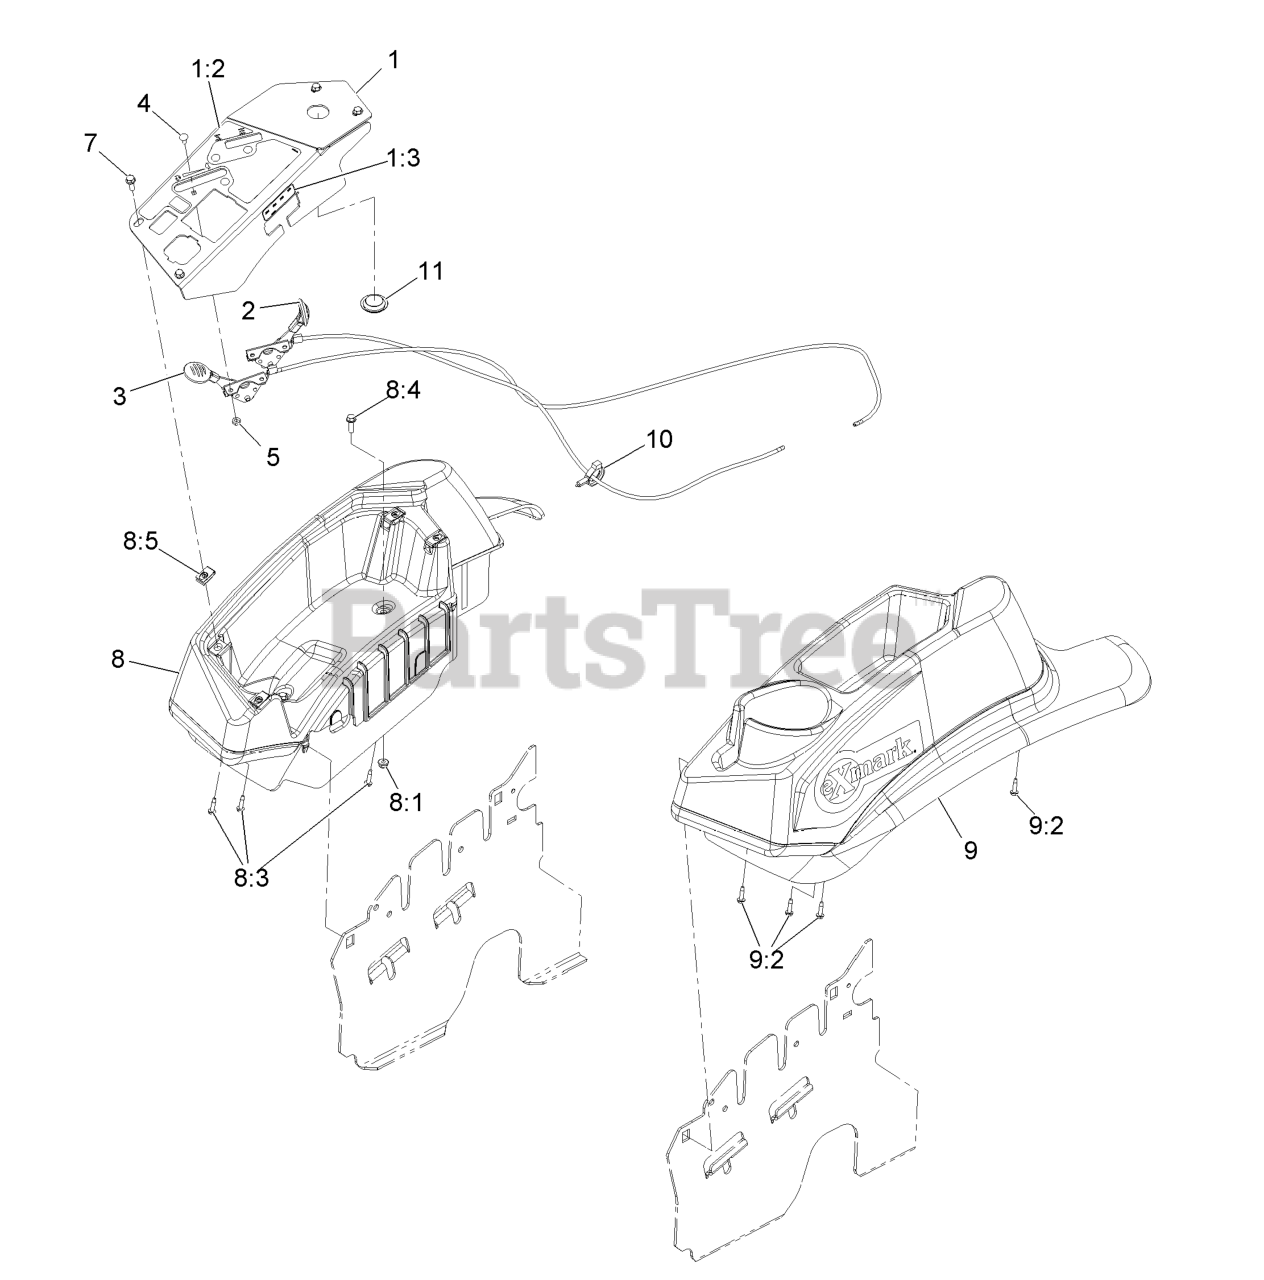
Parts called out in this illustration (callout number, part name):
1	CONSOLE,PANEL W/DECAL
1:2	DECAL-CONTROL PANEL
1:3	DECAL-FUSE
2	ASM, CHOKE CABLE
3	ASM,THROTTLE CABLE
4	BOLT-CARR
5	NUT-LOCK, NI
7	SCREW-HWH
8	CONSOLE,RH NARROW ASM
8:3	SCREW,THD FORM,HWH
8:4	SCREW-HWH
8:5	Nut-Retainer-Panel 1/4-20
9	CONSOLE.LH NARROW ASM
9:2	SCREW,THD FORM,HWH
10	CLAMP-HOSE
11	PLUG-PLASTIC
